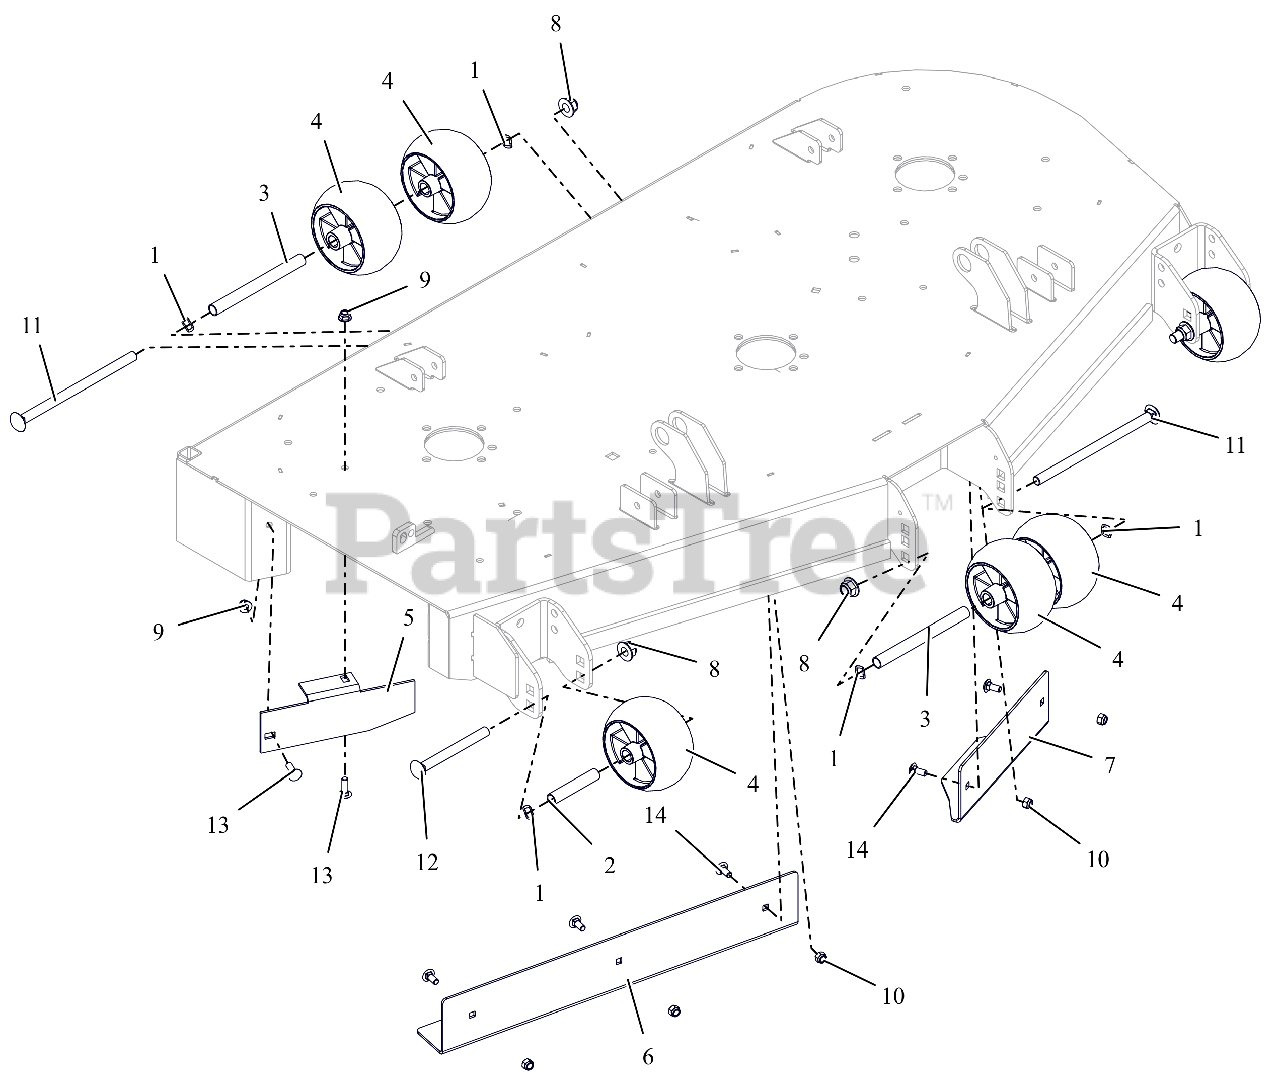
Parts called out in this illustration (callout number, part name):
1	WAVE WASHER .531X.781X.125FH
2	SPACER, .510X.625X3.35
3	SPACER, .510X.625X6.50
4	ANTI-SCALP WHEEL - 5X3 CTR
5	BAFFLE, DISCHARGE, 52"
6	BAFFLE, 52" RH VACUUM (RED)
7	BAFFLE, 52" LH VACUUM (RED)
8	NUT,NYL-FLG .50-13 GF ZCC
9	NUT,NYL-FLG .31-18 GF ZCC
10	NUT,NYL .31-18 G5 ZCC
11	BLT, RHSN .50-13X8.50 G5 ZCC
12	BLT, RHSN .50-13X5.00 G5 ZCC
13	BLT,RHSN .31-18X1.00 G5 ZCC
14	BLT,RHSN .31-18X.75 G5 ZCC
